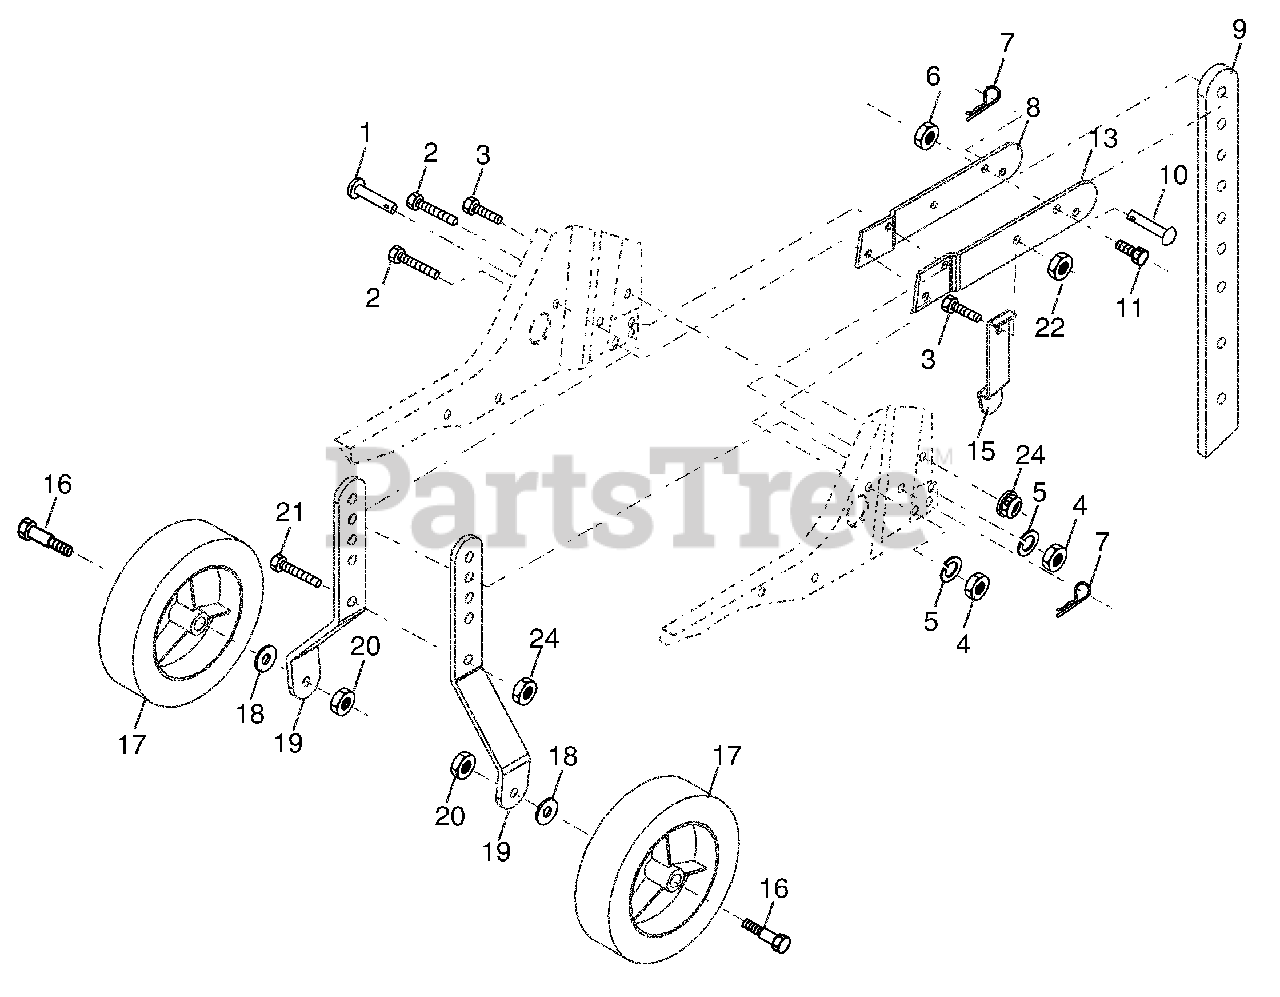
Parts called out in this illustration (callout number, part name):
1	Pin, Clevis
2	Bolt, Hex 5/16-18 x 1-1/4
3	Bolt, Hex 5/16-18 x 3/4
4	Nut, Hex 5/16-18
5	Washer, Lock 5/16
6	Locknut, w/washer 3/8-16
7	Clip, Hairpin
8	Support, Depth Stake, R.H.
9	Stake, Depth
10	Pin, Clevis
11	Bolt, Hex, Fin 3/8-16 x 1-3/4
13	Support, Depth Stake, L.H.
15	Spring, Stake
16	Bolt, Shoulder
18	Washer 13/32 x 13/16 x 11 Ga.
19	Bracket, Wheel
20	Locknut, Crown 3/8-16
21	Bolt, Hex 5/16-18 x 1
22	Locknut, w/insert 5/16-18
24	Nut Lock Hex Flange
